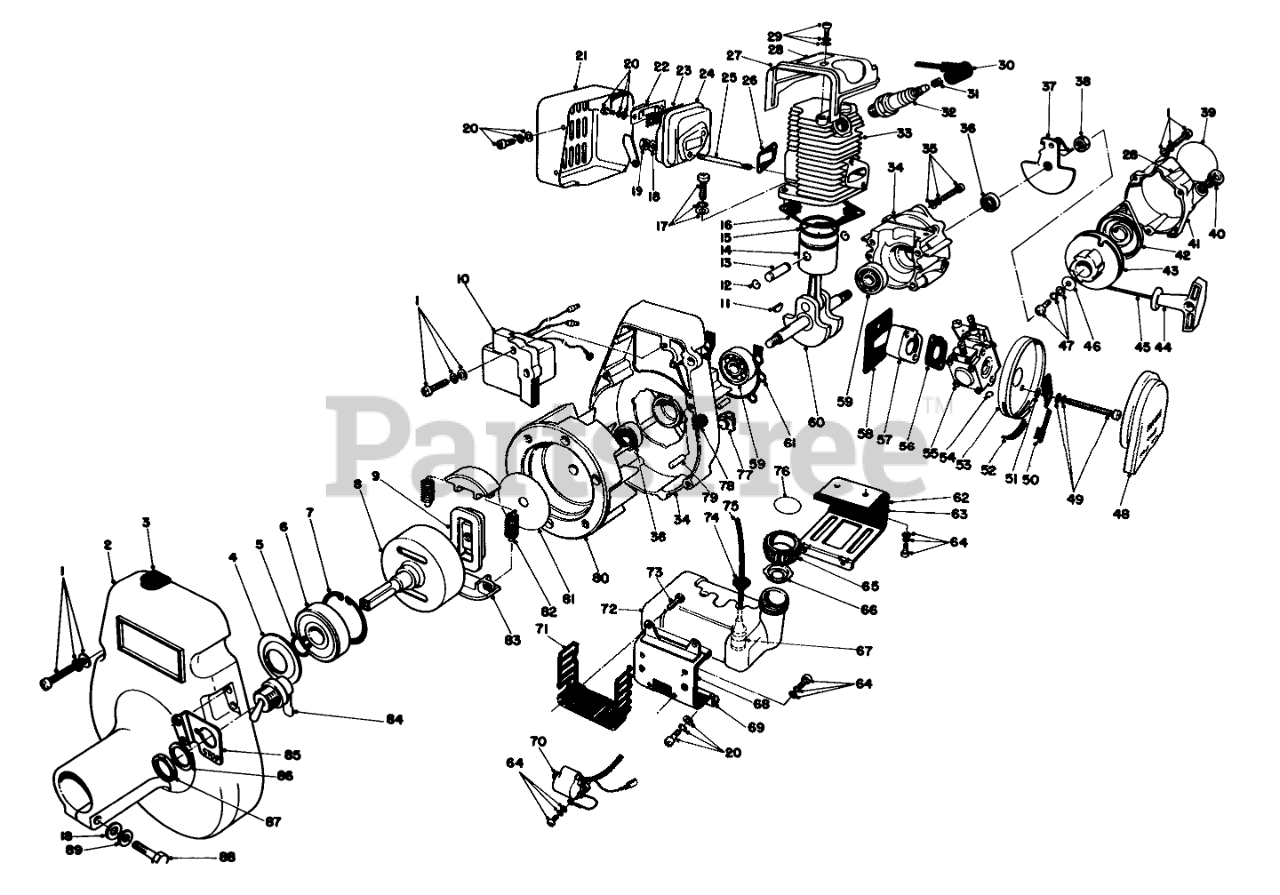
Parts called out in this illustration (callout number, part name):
1	SCREW
2	Fan Cover
4	Stopper
5	Circlip
6	Ball Bearing
7	Circlip
8	Clutch Drum
9	Clutch Boss
10	MODULE CDI-WILLMAR
11	Woodruff Key
12	Circlip, Piston Pin
13	Piston Pin
14	Piston
15	PISTON RING
16	Gasket, Cylinder Base
17	Screw
18	WASHER
19	Locknut
20	SCREW
21	Muffler Cover
22	Lid-Muffler
23	Screen
24	Muffler Body
25	STUD BOLT
26	Gasket, Muffler
27	Cylinder Cover
28	Decal-Hot Surface
29	SCREW
30	Cap-Spark Plug
31	Coil Spring-Plug Cap
33	Cylinder
34	Crankcase Set
35	SCREW
36	Oil Seal
37	Ratchet Assembly
39	Decal
40	Rope Guide
41	Starter Case
42	REWIND SPRING
43	Recoil Drum
44	Starter Handle
45	Rope-Starter
46	WASHER-WILLMAR
47	Screw
48	AIR FILTER
49	SCREW
50	CHOKE SHUTTER
51	CHOKE SHUTTER SPACER
52	Grommet
53	Case-Air Cleaner
54	Clip Fuel Pipe
55	Carburetor Assembly
56	Gasket
57	Insulator
58	INSULATOR GASKET-WILLMAR
59	Bearing
60	Crankshaft Assembly
61	Gasket-Crankcase
62	Bracket-Fuel Tank
63	Cushion
64	Screw
65	Cap-Fuel Tank
66	Check Valve
67	FUEL STRAINER
68	Cushion
69	Bracket-Fuel Tank
70	IGNITION COIL-WILLMAR
71	Dust Filter
72	FUEL TANK
73	Screw
74	GROMMET
75	Fuel Hose
76	Decal Fuel Mix
77	Cord Holder
78	Grommet
79	Knockpin
80	Flywheel
81	Side Plate
82	CLUTCH SPRING
83	CLUTCH SHOE
84	Switch (Incl. Ref. #86 & 87)
85	Bracket-Switch
86	Washer
87	Nut
89	Washer
